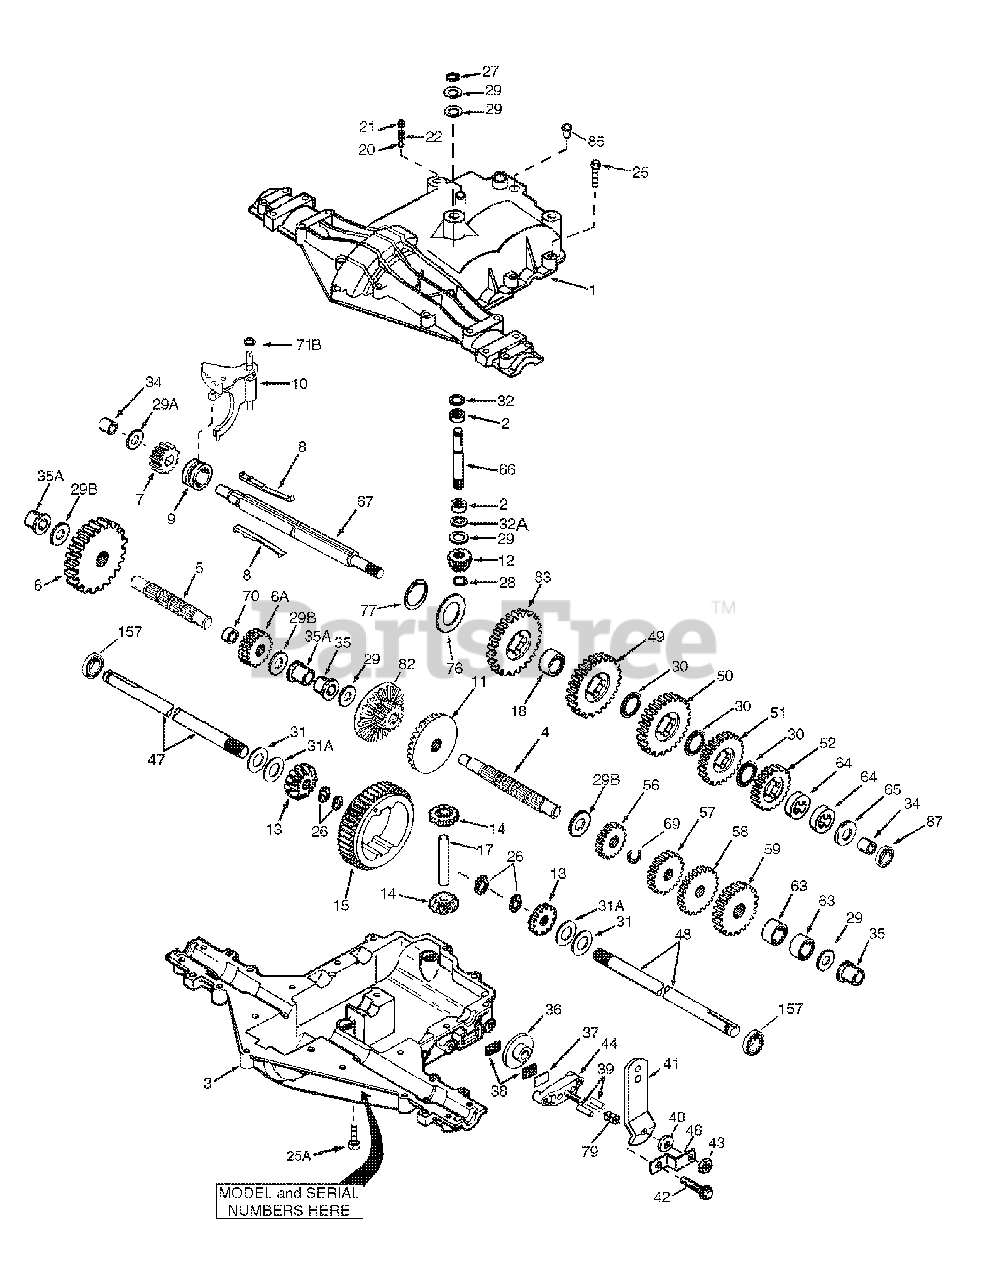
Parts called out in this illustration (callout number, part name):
1	Transaxle Cover
2	Needle Bearing (1/2" long)
3	Transaxle Case
4	Countershaft
5	Output Shaft
6	Spur Gear (38T-PM/SER)
6A	Spur Gear (15T-PM/SER)
7	Spur Gear (11T-PM/SER)
8	Shift Key Set (Qty. 2)
9	Shift Collar
10	Shift Rod & Fork Assembly
11	Bevel Gear (30T-PM)
12	Input Bevel Pinion (13T-PM)
13	Bevel Gear 13T (Incl. ref. 13 & 14)
14	Bevel Gear 13T (Incl. ref. 13 & 14)
15	Ring Gear (43T)
18	Spacer (1.130" x .695")
20	Ball (Stainless Steel 5/16" dia.)
21	Screw, 3/8-16 x 3/8"
25	Screw, 1/4-20 x 1-1/4"
25A	Screw, 1/4-20 x 1-3/8"
26	Retaining Ring-package of 2
27	Retaining Ring
28	Retaining Ring
29	Washer .627" ID .031"
29A	Thrust Washer (.563" ID x .031")
29B	Thrust Washer (.762" ID X .031")
30	Shift Washer (Cupped)
31	Washer .750" ID .56"
31A	Washer .750" ID .062
32	Oil Seal 5/8"
32A	O Ring (.823" OD)
34	Bushing (.563")
35	Flanged Bushing (.625" ID)
35A	Flanged Bushing (.751" ID)
36	Brake Disk
37	Brake Pad Plate
38	Brake Pad (pkg. of 2)
39	Dowel Pin .3125" x .750"
40	Washer .312" ID .059"
41	Brake Lever
42	Screw 1/4-20 x 1-3/8"
43	Lock Nut 5/16-24
44	Brake Pad Holder
47	Axle (10.719" long) (Incl. 26)
48	Axle (15.312" long) (Incl. 26)
49	Spur Gear (27T-PM/IC)
50	Spur Gear (22T-PM/IC)
51	Spur Gear (19T-PM/IC)
52	Spur Gear (16T-PM/IC)
56	Spur Gear (13T-PM/SER)
57	Spur Gear (18T-PM/SER)
58	Spur Gear (21T-PM/SER)
59	Spur Gear (24T-PM/SER)
63	Countershaft Spacer 1-1/8" x 3/8’’
64	Brake Shaft Spacer 1-3/8" x 3/8’’
65	Washer .563" ID .062
66	Input Shaft
67	Brake Shaft
69	Retaining Ring (.75" x .042")
70	Spacer (.890")
76	Flat Washer (1.128" ID x .058")
77	Retaining Ring (1.125" x .050")
82	Bevel (30T) & Spur Gear
83	Spur Gear (27T-PM/IC)
85	Oil Fill Plug
87	Oil Seal 9/16" ID
157	Oil Seal 3/4" ID
